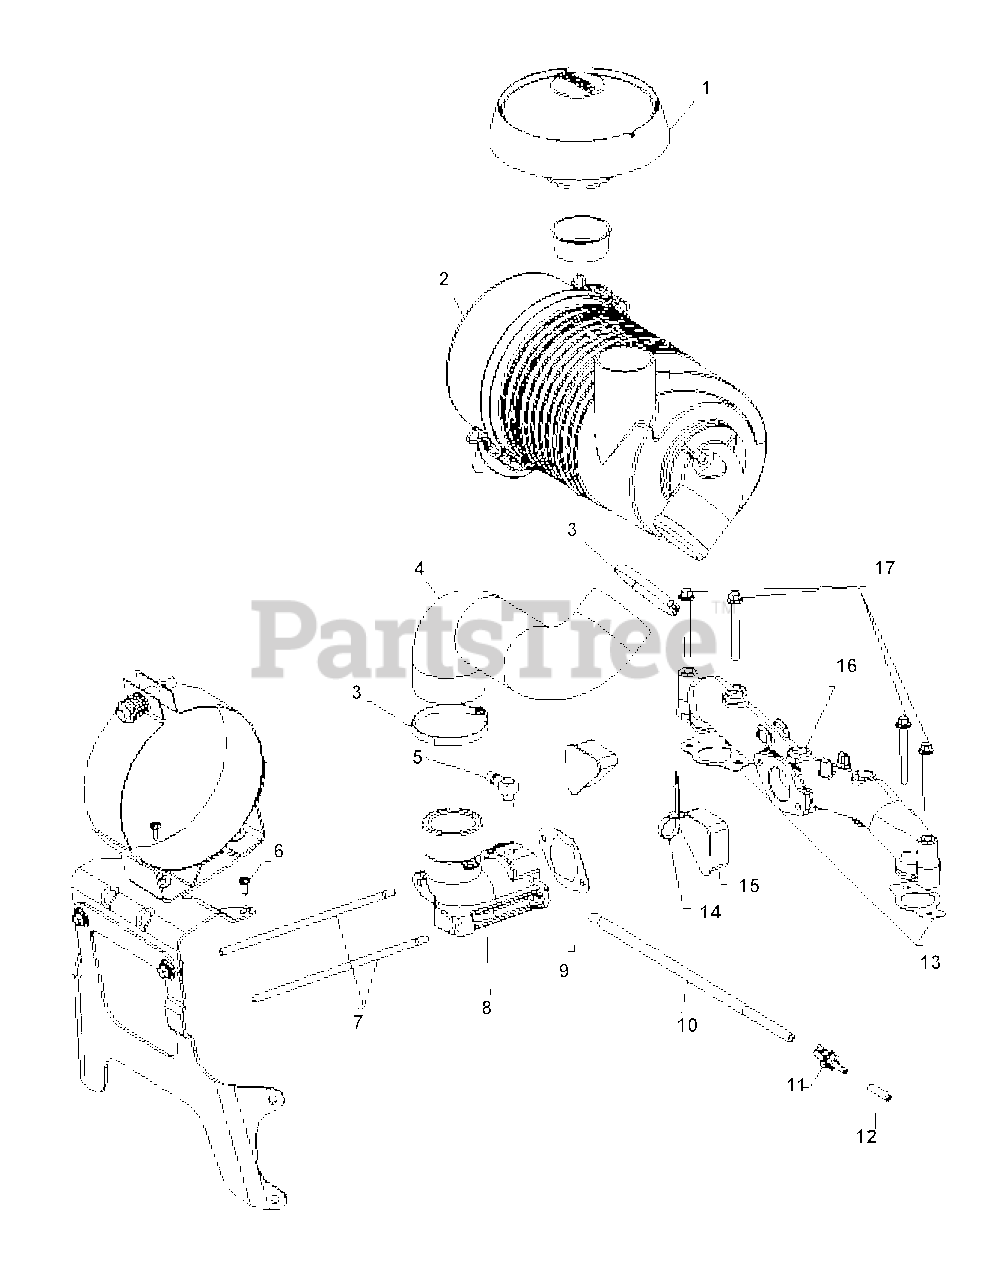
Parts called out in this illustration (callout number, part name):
4	Air Cleaner Hose
5	Hose Connector
6	Tap Screw, #8-18 x 1/2
7	Stud, M6 x 1.0 x 122
9	Air Cleaner Base Gasket
10	Evaporative Hose, 20"
11	Evaporative Connector
13	Intake Manifold Gasket
15	Blower Housing Cover
16	Intake Manifold
17	Flange Screw, M6 x 1.0 x 55
